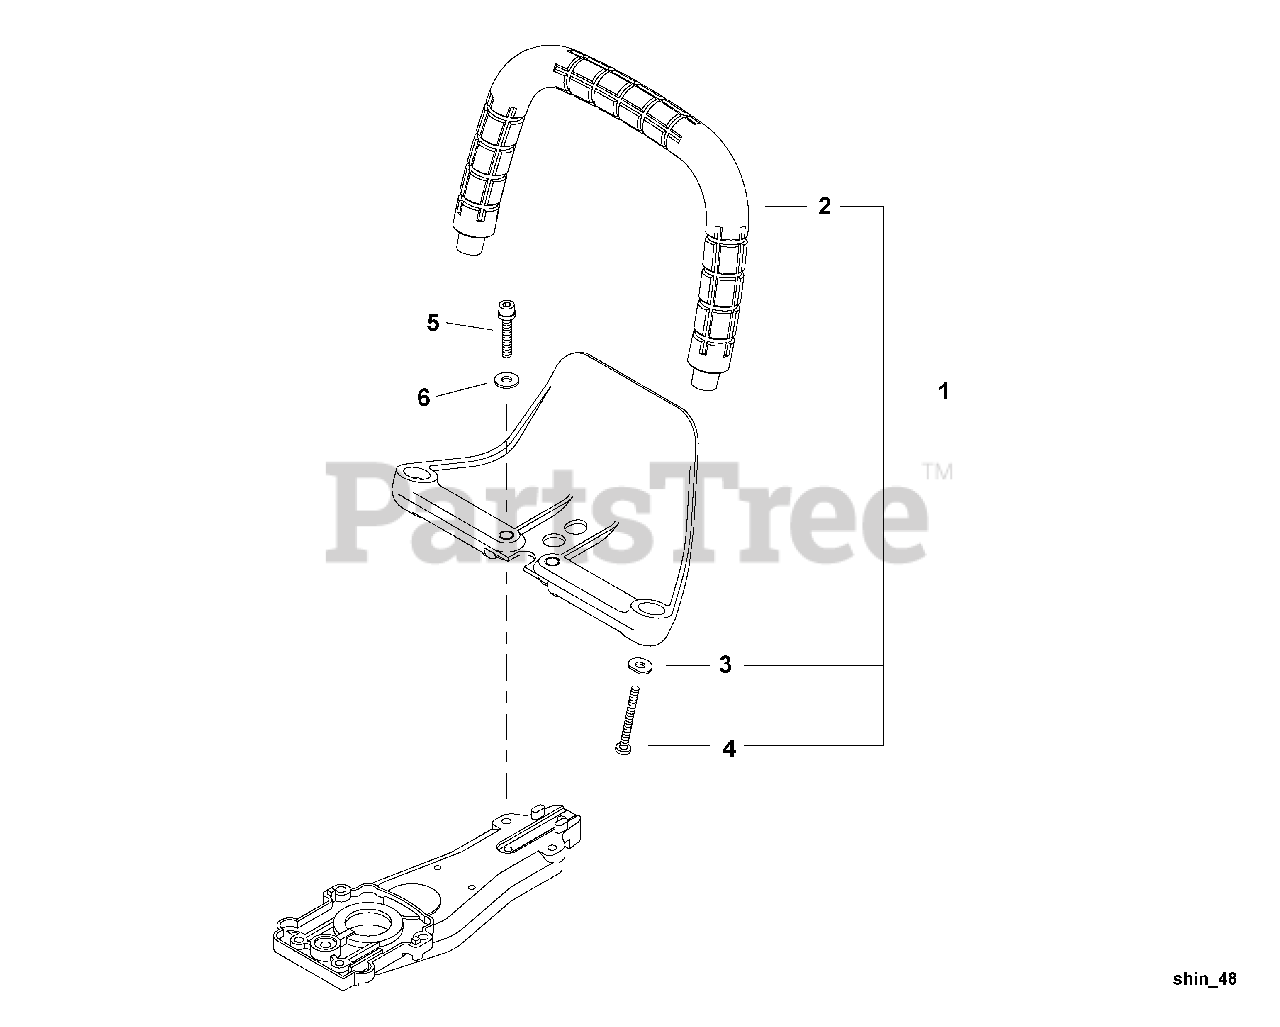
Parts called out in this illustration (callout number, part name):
1	HANDLE ASSY, FRONT
2	HANDLE, FRONT
4	BOLT, TAPPING 5
5	BOLT M6×30
6	WASHER Ø16ר6.5×1.6 MM
